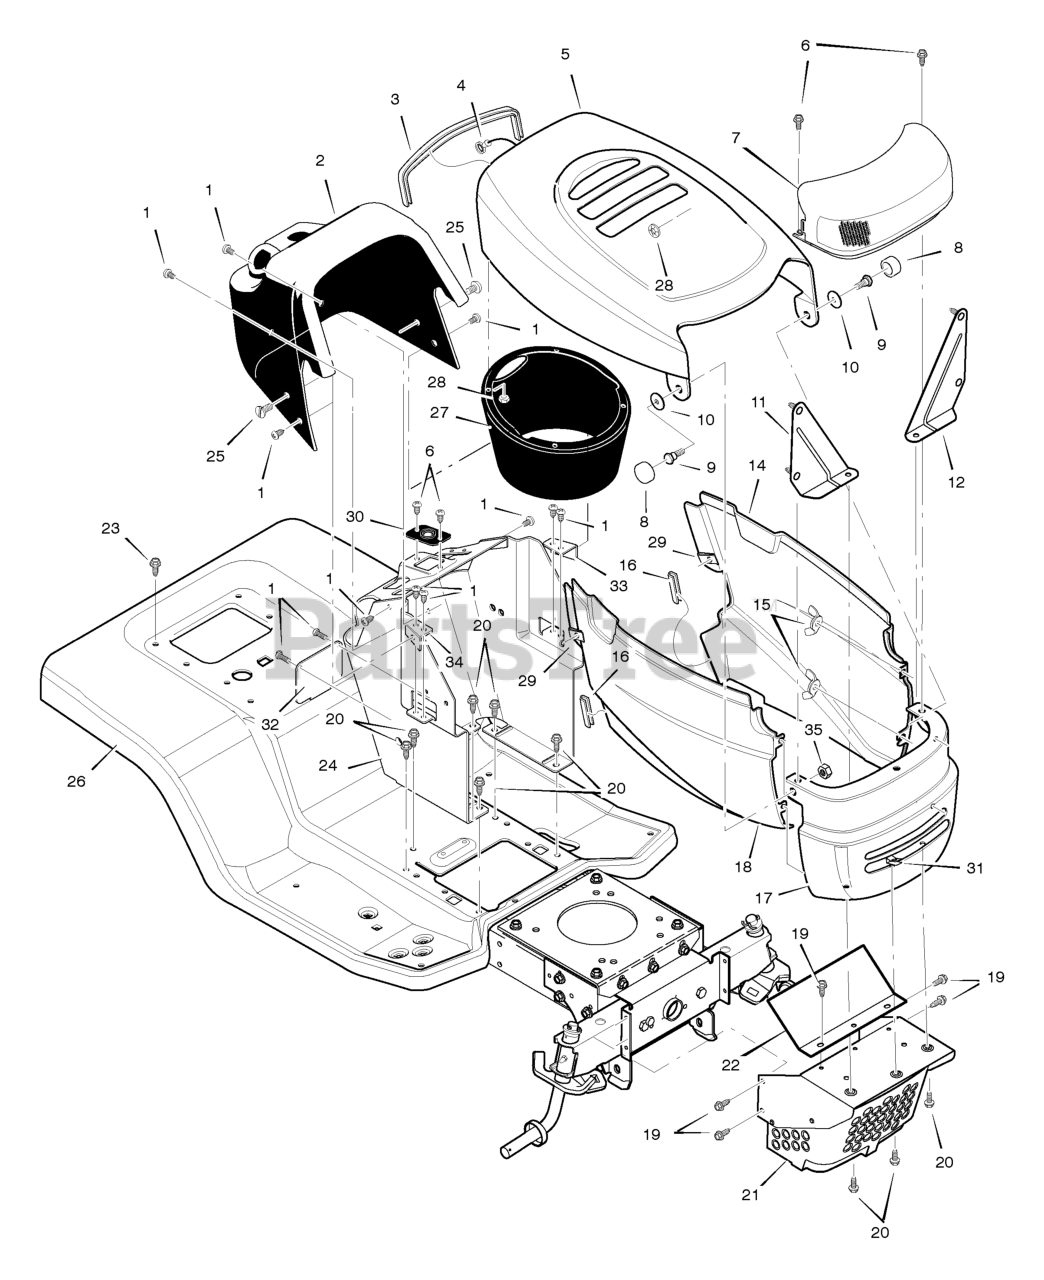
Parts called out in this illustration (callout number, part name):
1	Screw
3	Trim, Hood
5	Hood Assemnly
7	Lens & Reflector Assembly
8	Cap, Pivot
9	Bolt, Shoulder
10	Base, Pivot
11	Brace, Right Grille Assembly
12	Brace, Left Grille Assembly
14	Panel, Left Side
15	Wingnut
16	Trim 0.39"
18	Panel, Right Side
21	Guard Assembly, Muffler
22	Shield, Upper Heat
26	Deck, Seat
28	Retainer, Push
30	Bearing, Steering
32	Panel, Access
33	Bracket, Right Console
34	Bracket, Left Console
35	Nut
